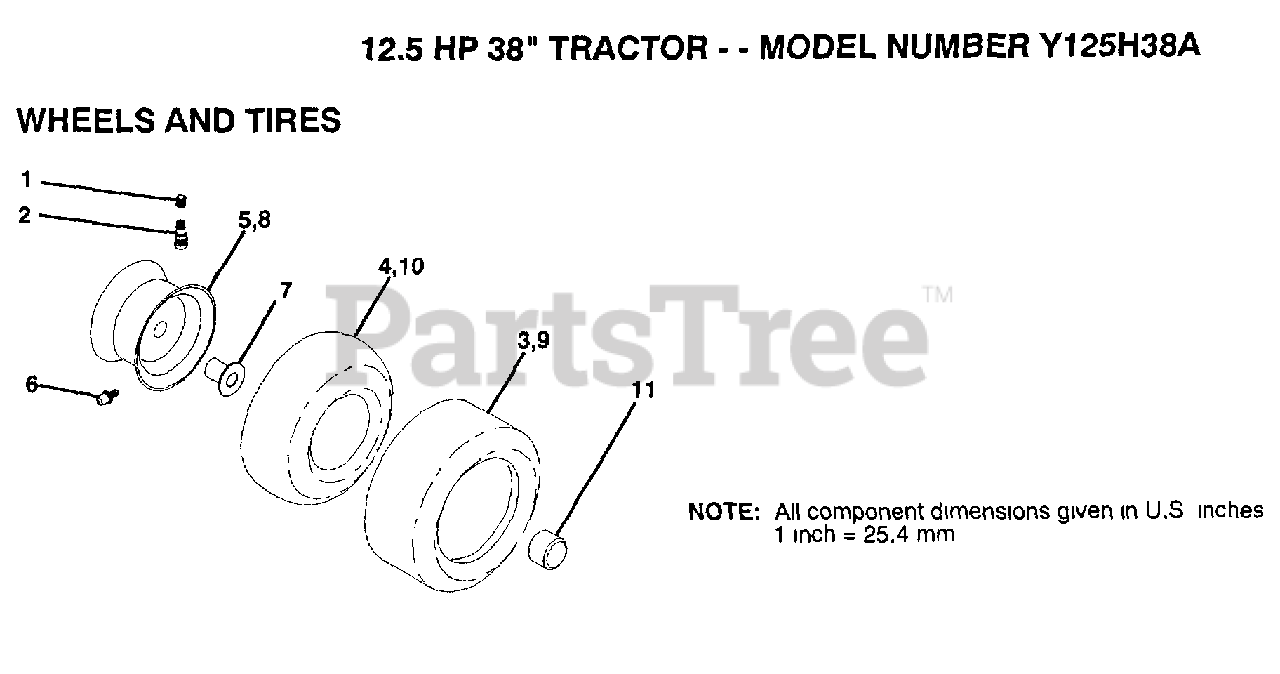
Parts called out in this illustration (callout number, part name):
1	VALVE CAP
2	VALVE STEM LT
4	TUBE.5.3/4.5/6
6	FITTING LT
7	"FLANGE, BEARING"
10	TUBE.18X9.5-8
11	HUB CAP
